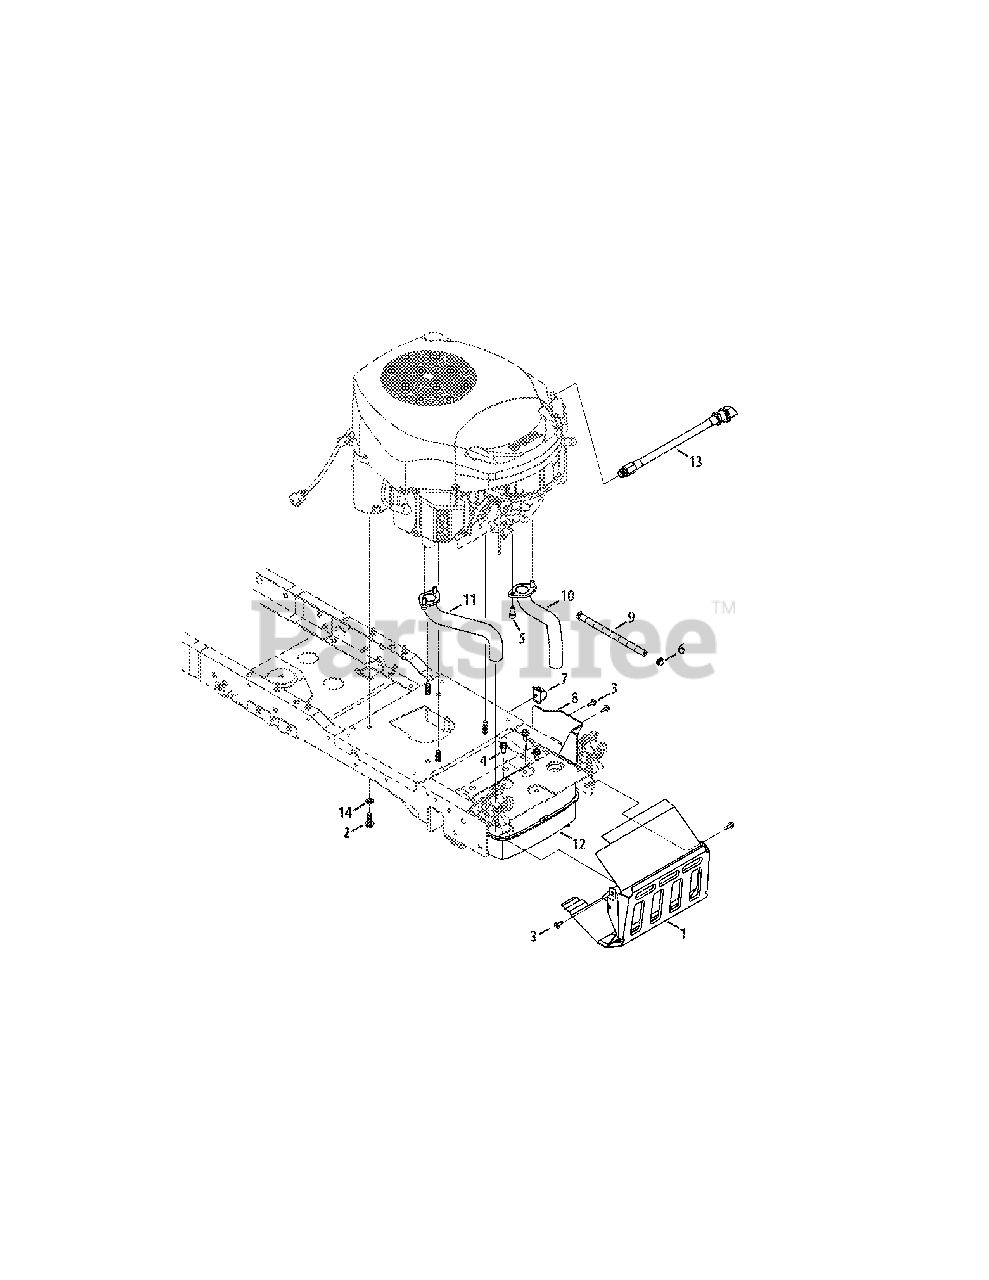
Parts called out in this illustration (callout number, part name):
1	Shield Ass’y, Muffler
2	Screw, Self-tapping, 3/8-16, 1.0
3	Screw, M6-1 x .625
4	Screw, Self-tapping, M8-1.25, .750
5	Screw, Sokt Head, 5/16-18, .750
6	Clamp, Hose, .490 Dia.
7	Push Mount Wire Clip, .750
8	Muffler Shield
9	Hose, Fuel, Low Permeation, 1/4
10	Exhaust Pipe, LH
11	Exhaust Pipe, RH
12	Muffler, Kohler
13	Drain, Oil
14	Lock Washer, 3/8
